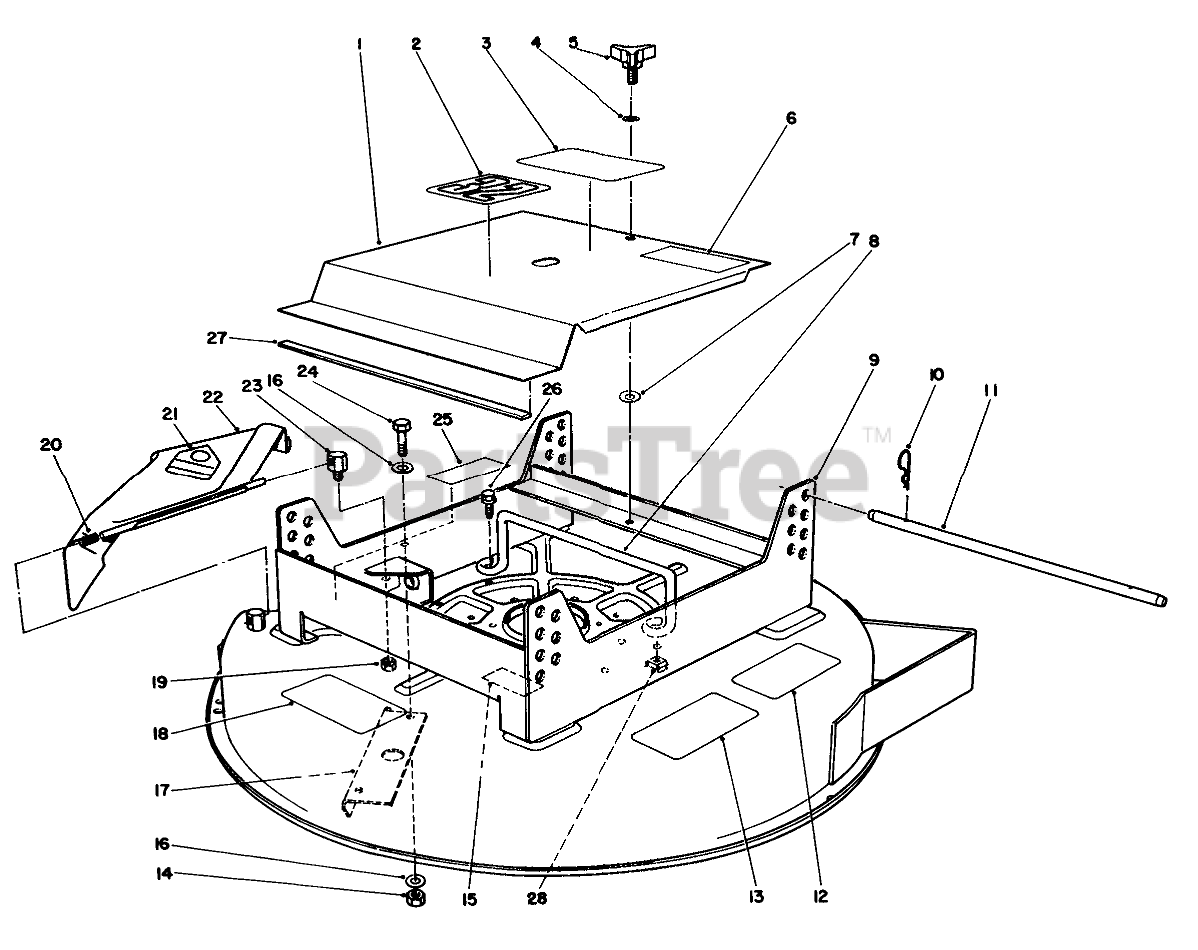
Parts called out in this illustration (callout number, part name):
1	Cover (Incl. Ref. #2-7 & 27)
2	DECAL
3	DECAL-PROLINE
4	WASHER-FLAT
5	Knob
6	DECAL-HOT
7	RING-RETAINING
8	GUIDE-BELT
9	32 INCH DECK ASM
10	PIN-HAIR
11	ROD-SUPPORT
12	DECAL
13	Decal
14	NUT-LOCK, NI
15	DECAL-DANGER
16	WASHER-PLAIN
17	Baffle Deck
18	DECAL-DANGER, THROWN OBJECT
19	NUT-LOCK, SIDE
20	SPRING
21	DECAL-DANGER
22	Deflector Assembly (Incl. Ref. #21)
23	POST-PIVOT
24	SCREW-HH
25	DECAL-DANGER
26	SCREW-HHF
27	STRIP-MAGNETIC
28	NUT-RETAINER
